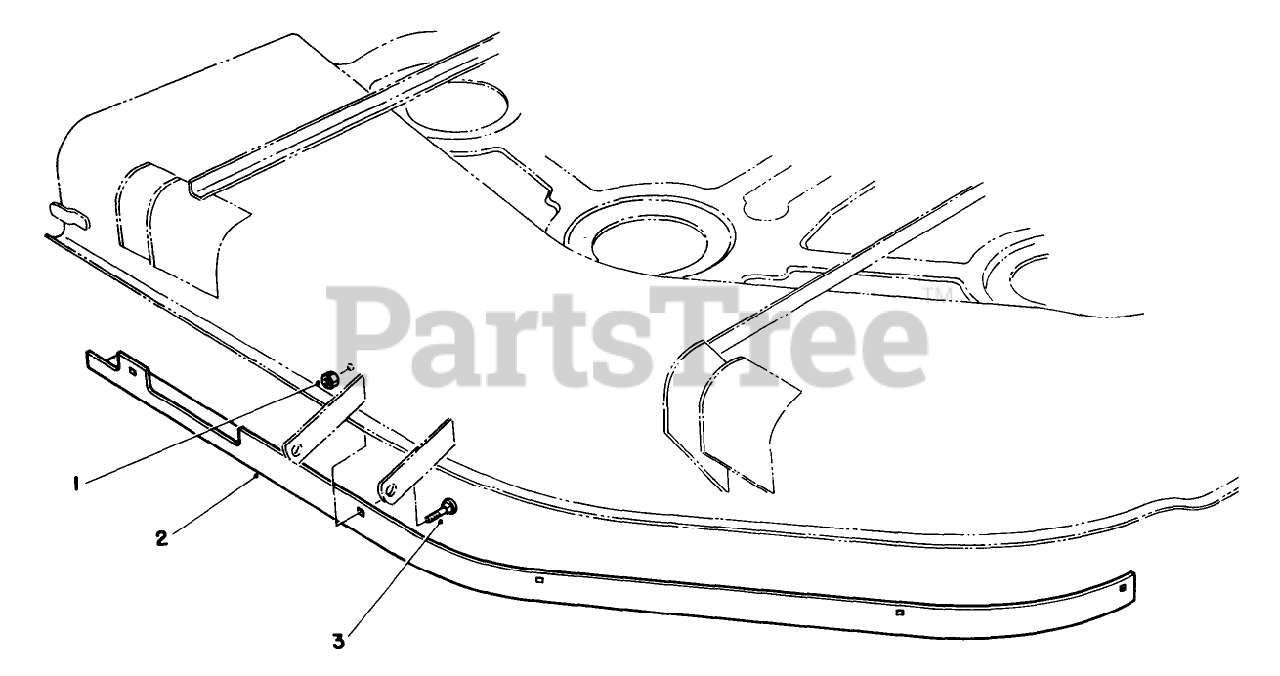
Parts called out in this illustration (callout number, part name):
1	NUT-LOCK, NI
2	Baffle
3	SCREW-CARR
